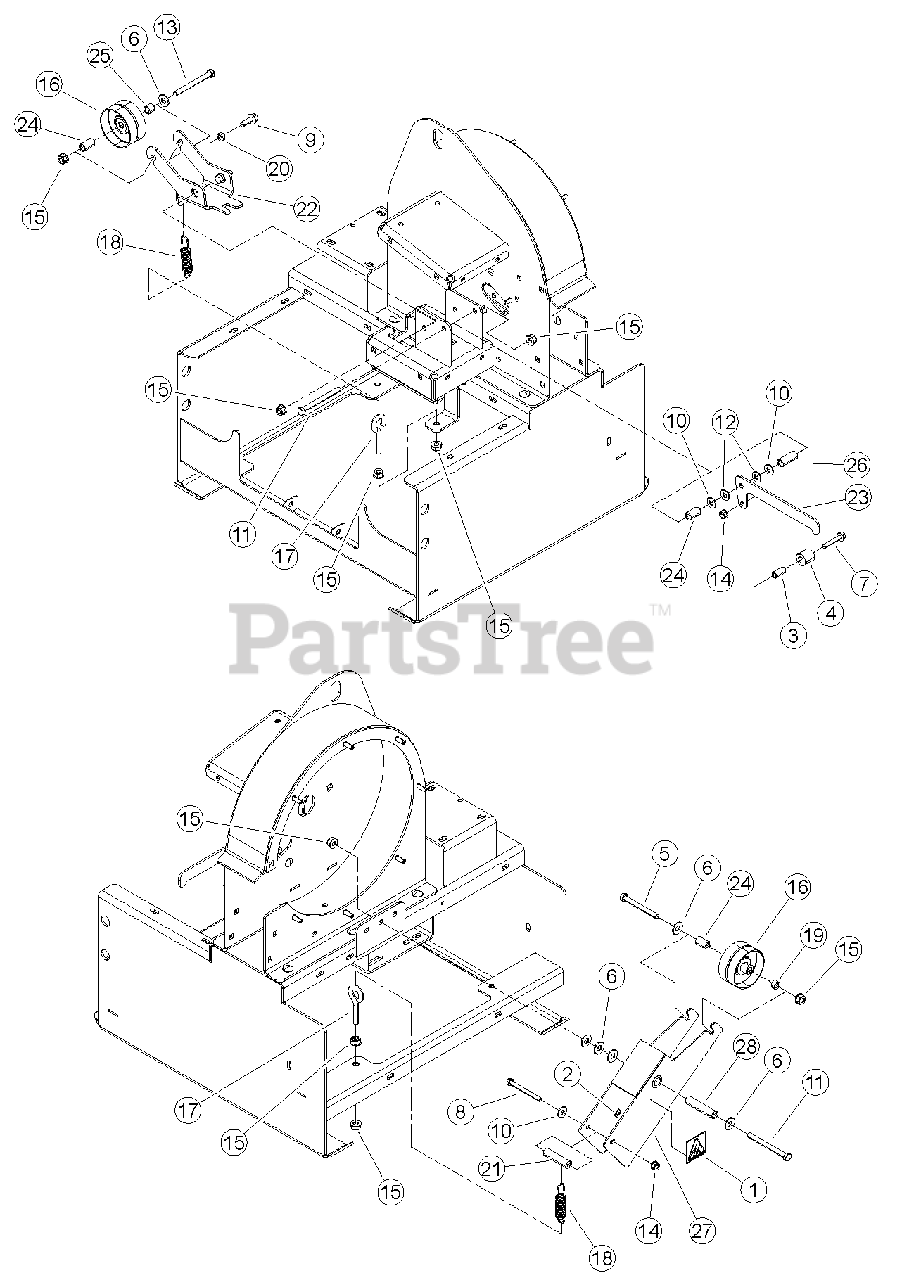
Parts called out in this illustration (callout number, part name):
1	DECAL, SHIELD DANGER ISO
2	FITTING, 1/4 SELF-TAP GREASE
3	SPACER, 0.5 X 1.00
4	ROLLER, 0.5 X 1.00 X 1.00 NYLON
5	BOLT, 3/8 X 3-1/2" HEX HD GR5 ZP
6	WASHER, 3/8" FLAT ZP
7	BOLT, 5/16 X 1-3/4" FLANGE NC
8	BOLT, 5/16 X 3-1/4" GR5 HCPS
9	BOLT, 3/8 X 1 FLANGE NC
10	WASHER, 5/16" FLAT ZP
11	BOLT, 3/8 X 4" HHCS GR5 NC ZP
12	WASHER, FLAT 3/8" NYLON .062 TH
13	BOLT, 3/8 X 3-3/4 HEX HD GR5 ZP
14	NUT, 5/16-18 NYLOCK FLANGE
15	NUT, 3/8-16 NYLOCK FLANGE
16	PULLEY, 3-1/4 FLAT IDLER
17	EYE BOLT, G-2, 3/8 X 2" ZP
18	SPRING, 3/4" OD EXTENSION
19	BUSHING
20	SPACER, IDLER PIVOT
21	SPACER, .63 X 2.44
22	BRACKET, IDLER
23	LEVER, ENGAGEMENT
24	SPACER, .63 X 1.035
25	SPACER,.63 X .515
26	SPACER, .63 X 1.560
27	WELDMENT, IDLER
28	SPACER, .63 X 2.880
